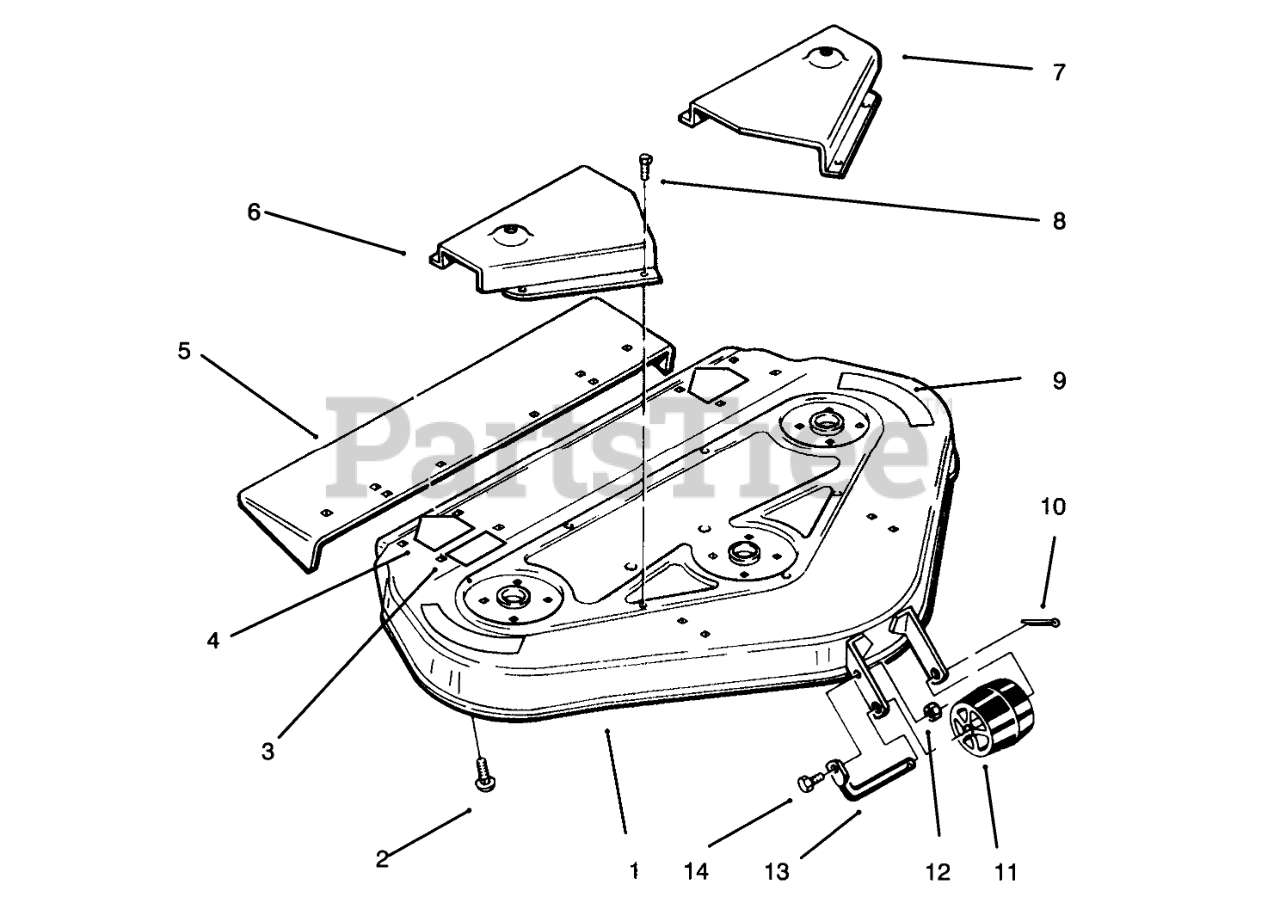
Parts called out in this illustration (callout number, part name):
1	Deck (Incl Ref #4 & 9)
2	BOLT-CARR
3	DECAL-HEIGHT & BELT
4	DECAL-DANGER
5	Chute Extension
6	Belt Cover RH
7	Cover-Belt
8	SCREW -4
9	DECAL - DANGER
10	PIN-COTTER
11	ROLLER ASSY
12	NUT-LOCK, NI
13	ROLLER-SHAFT
14	SCREW-HH
